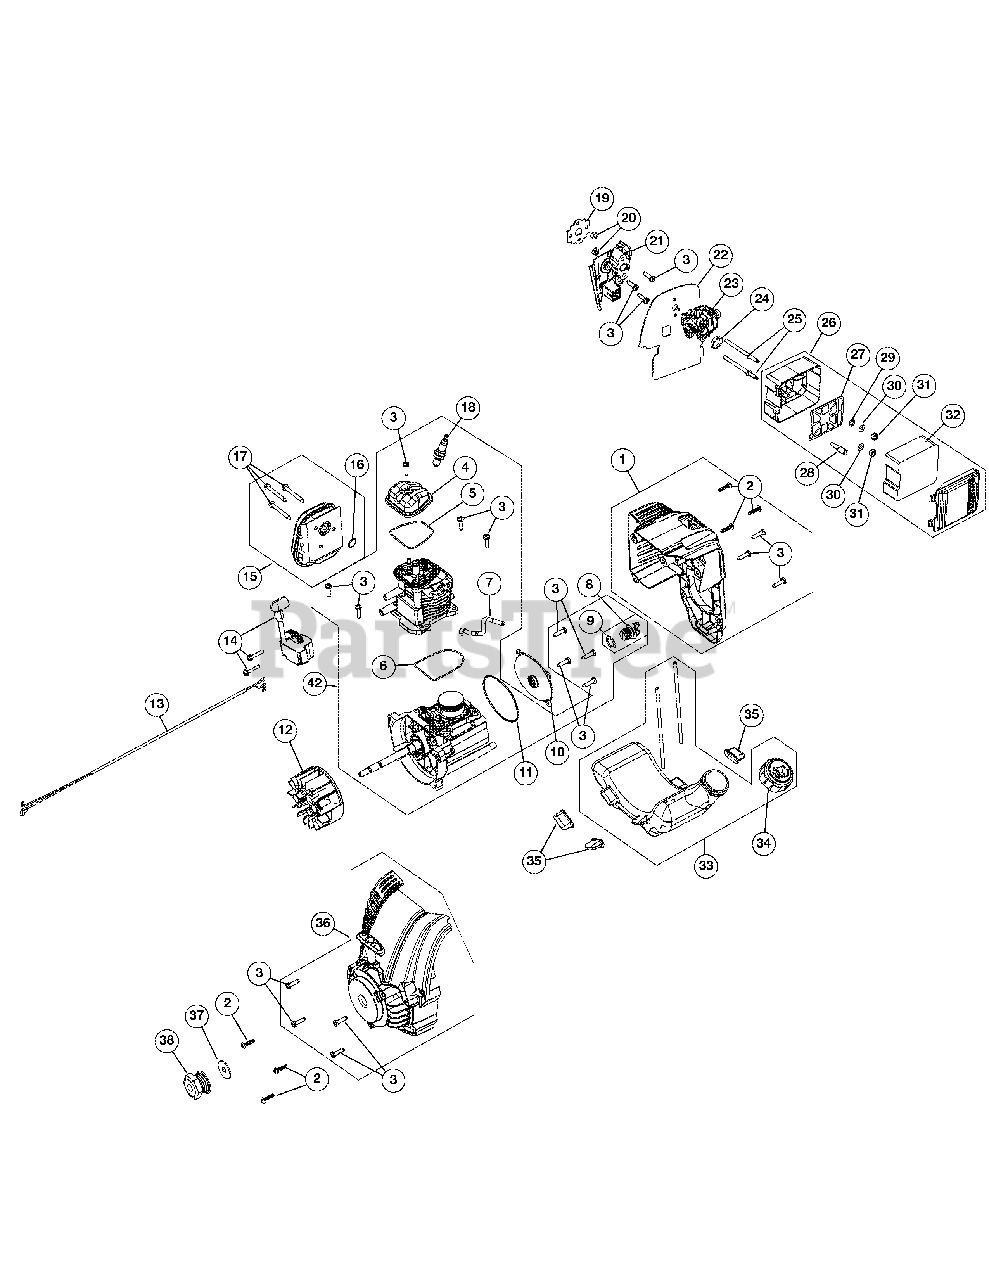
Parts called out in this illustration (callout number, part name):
1	Engine Cover Assembly (Incl. Ref No. 2 & 3)
2	Cover Screw
3	Starter Screw
4	Rocker Cover
5	Rocker Cover O-Ring
6	Cylinder O-Ring
7	Breather Hose
8	Oil Plug (Incl. Ref No. 9)
9	Oil Plug O-Ring
10	Crankcase Cover
11	Crankcase Cover O-ring
12	Flywheel Assembly
13	Lead Wires
14	Module Assembly
15	Muffler Assembly (Incl. Ref No. 16 & 17)
16	Muffler Gasket
17	Muffler Screw
18	Spark Plug
19	Insulator Gasket
20	Nut
21	Insulator
22	Carburetor Gasket
23	Carburetor w/Primer
24	Air Cleaner O-Ring
25	Air Filter Mounting Screw
26	Air Cleaner Cover Assembly (Incl. Ref No. 27-32)
27	Air Filter Plate
28	Breather Tube Assembly
29	Grommet Washer
31	Nut
32	Air Filter
33	Fuel Tank Assembly w/Fuel Lines (Incl. Ref No. 35)
34	Fuel Cap
35	Fuel Tank Pads
36	Starter Housing Assembly (Incl. Ref No. 3 & 37-45)
37	Washer
38	Drive Shaft Pulley
42	Shortblock Assembly
